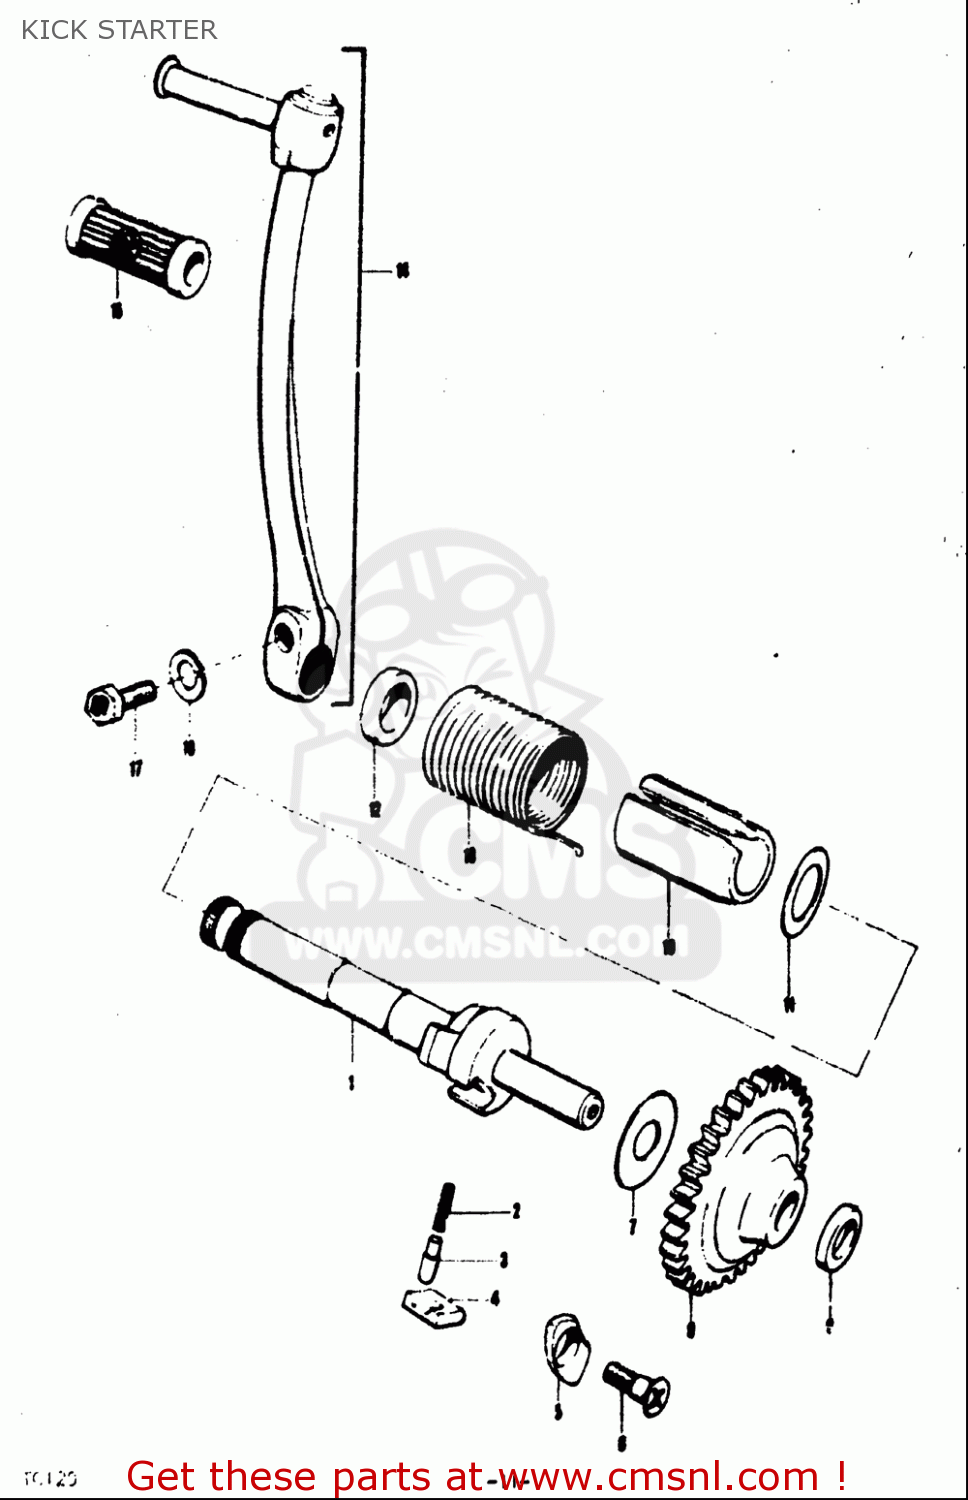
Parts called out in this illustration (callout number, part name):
2	SPRING
3	PIN(5X15.5)
5	LIFTER,KICK STARTER PAWL
6	SCREW(6X19)
7	WASHER
9	SPACER
10	GUIDE,KICK STARTER SFT SPRING
11	WASHER(16X30X1)
12	SEAL,OIL(16X30X8)
15	RUBBER,KICK STARTER PEDAL
16	WASHER,LOCK
17	BOLT
